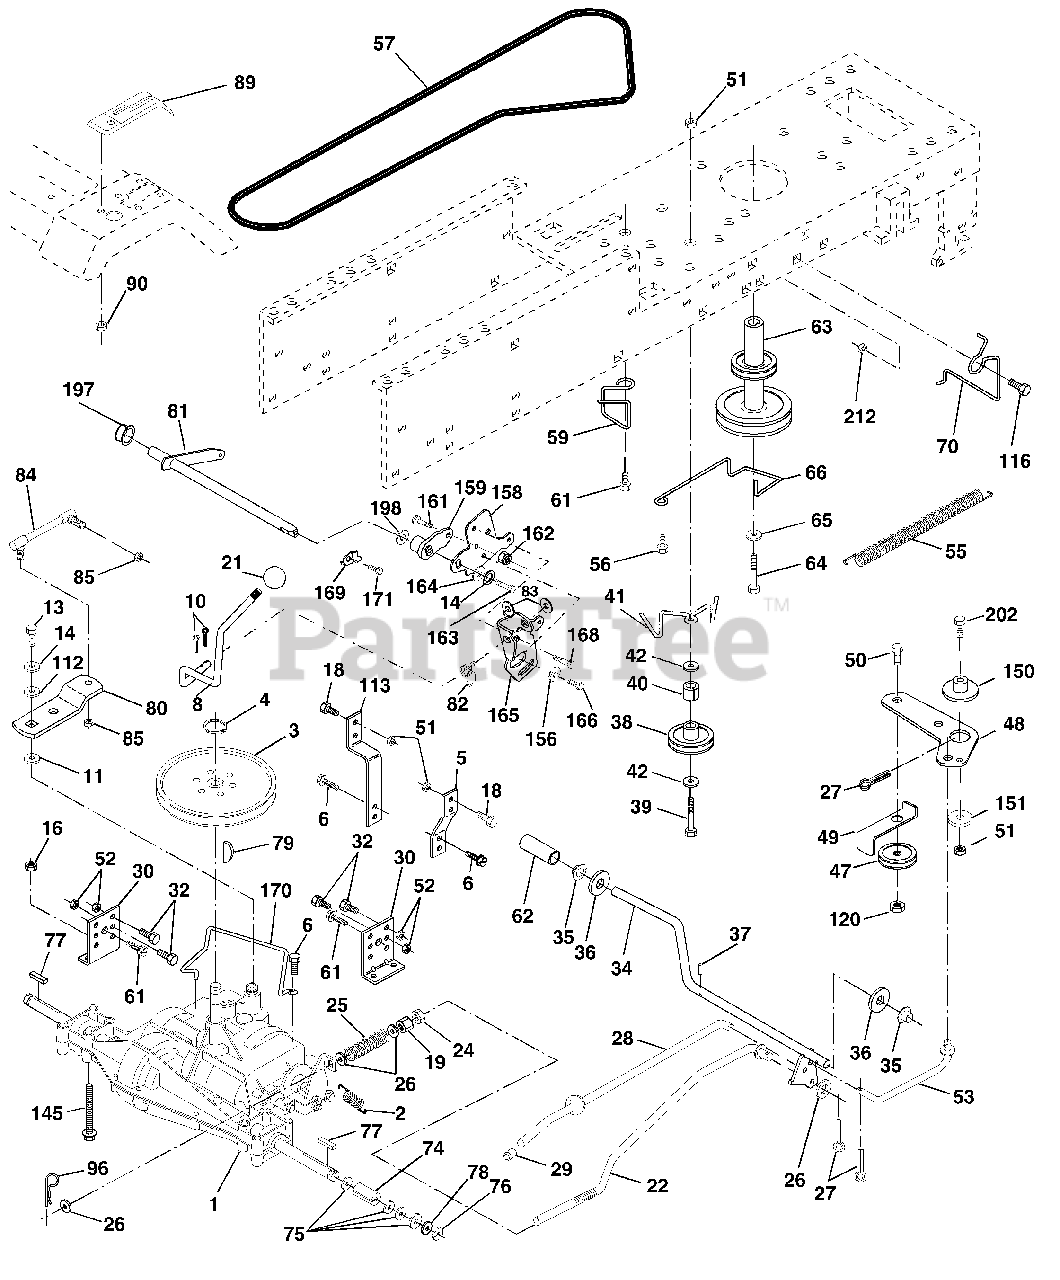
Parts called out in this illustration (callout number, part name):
2	Spring Return Brake T/a Zinc
3	Pulley Transaxle 18" tires
4	Ring Retainer # 5100-62
5	Strap Torque 30 Degrees
6	Screw 5/16-18 x 3/4
8	Rod Shifter Fender Adj Lt
10	Pin Cotter 1/8 x 1 Cad
11	Washer Plate Shf 388 Sq Hole
13	Bolt 1/4-28 Unf Gr 8 W/Patch
14	Washer Lock Hvy Helical 1/4
16	Nut Lock
18	Bolt, Fin Hex 3/8-16 UNC x 1 Gr. 5
19	Nut Lock 3/8-16 Unc
21	Knob
22	Rod Brake Blk Zinc 26 840
24	Nut Hex Jam 3/8-16 Unc
25	Spring Rod Brake 2 00 Zinc
26	Washer 13/32 X 13/16 X 16 Ga
27	Pin Cotter 1/8 X 3/4 Cad
28	Rod Brake Parking LT/YT
29	Cap Brake Parking
30	Bracket Mtg Transaxle
32	Bolt Hex Hd 5/16-18unc X 3/4
34	Shaft Asm Pedal Foot
35	Bearing Nylon Blk 629 Id
36	Washer 21/32 X 1 X 16 Ga
37	Pin Roll 3/16 X 1"
38	Pulley Idler Flat
39	Bolt Fin Hex 3/8-16unc X 3
40	Spacer Split
41	Keeper Belt Retainer Idler
42	Washer 13/32 X 13/16 X 12 Ga
47	Pulley Idler V Groove Plastic
48	Bellcrank Asm
49	Retainer Belt Style Spring
50	Bolt Hex Hd 3/8-16unc X 1-1/2
51	Nut Crownlock 3/8-16 Unc
52	Nut Crownlock 5/16-18 Unc
53	Link Clutch
55	Spring Return Clutch 6 75
56	Bolt Fin Hx 3/8-16 X 1.00
57	V-Belt Ground Drive
59	Keeper Belt Span Ctr
61	Screw 3/8-16 x 3/4
62	Cover Pedal Blk Round
63	Engine Pulley LT/YT
64	Bolt Hex
65	Washer Lock Hvy Hlcl Spr 7/16
66	Keeper Belt Engine Foolproof
70	Guide Belt Mower Drive RH
74	Spacer Axle
75	Washer 25/32 X 1 1/4 X 16 Ga
76	E-ring #5133-75
77	Key Square 2 0 X 1845/ 1865
78	Washer 25/32 X 1-5/8 X 16 Ga
79	Key Woodruff
80	Arm Shift
81	Shaft Asm Cross Tapered 20"t
82	Spring Torsion T/a
83	Washer 17/32 X 3/4 X 16 Ga
84	Link Transaxle
85	Nut Lock Center 1/4 - 28 FNTHD
90	Nut Self-thd Wsh-hd 1/4 Zinc
96	Retainer Spring
112	Washer 9/32 x 3/4 x 10 Ga.
113	Strap Torque Lh
116	Bolt Rdhd Sq Neck 3/8-16 x 1
120	Nut Lock 3/8-16
145	Bolt Hex 5/16-18 Gr. 5
150	Spacer
151	Washer 13/32 x 2 x 10
156	Washer Srrted 5/16 ID x 1.125
158	Bracket Shift Mount
159	Hub Tapered Flange Shift lt
161	Bolt Rdhd Sqnk 1/4-20 x 3/4 Gr 5
162	Nut Crownlock 1/4-20 Unc
163	Bolt Hex Fin 1/4-20 Unc x 1 Gr 5
164	Washer 5/8 x .281 x 10 Ga
165	Bracket Pivot Lever
166	Screw 5/16-18 x 5/8
168	Bolt Shoulder 5/16-18 x .561
169	Plate Fastening Lt
170	Keeper Belt Transaxle
171	Screw Thdrol 3/8-16 x 1/2
197	Nyliner, Snap - in
198	Washer, Nyl.
202	Bolt, Carriage 3/8 - 16 x 1 3/4
212	Nut Hex Flange Lock
